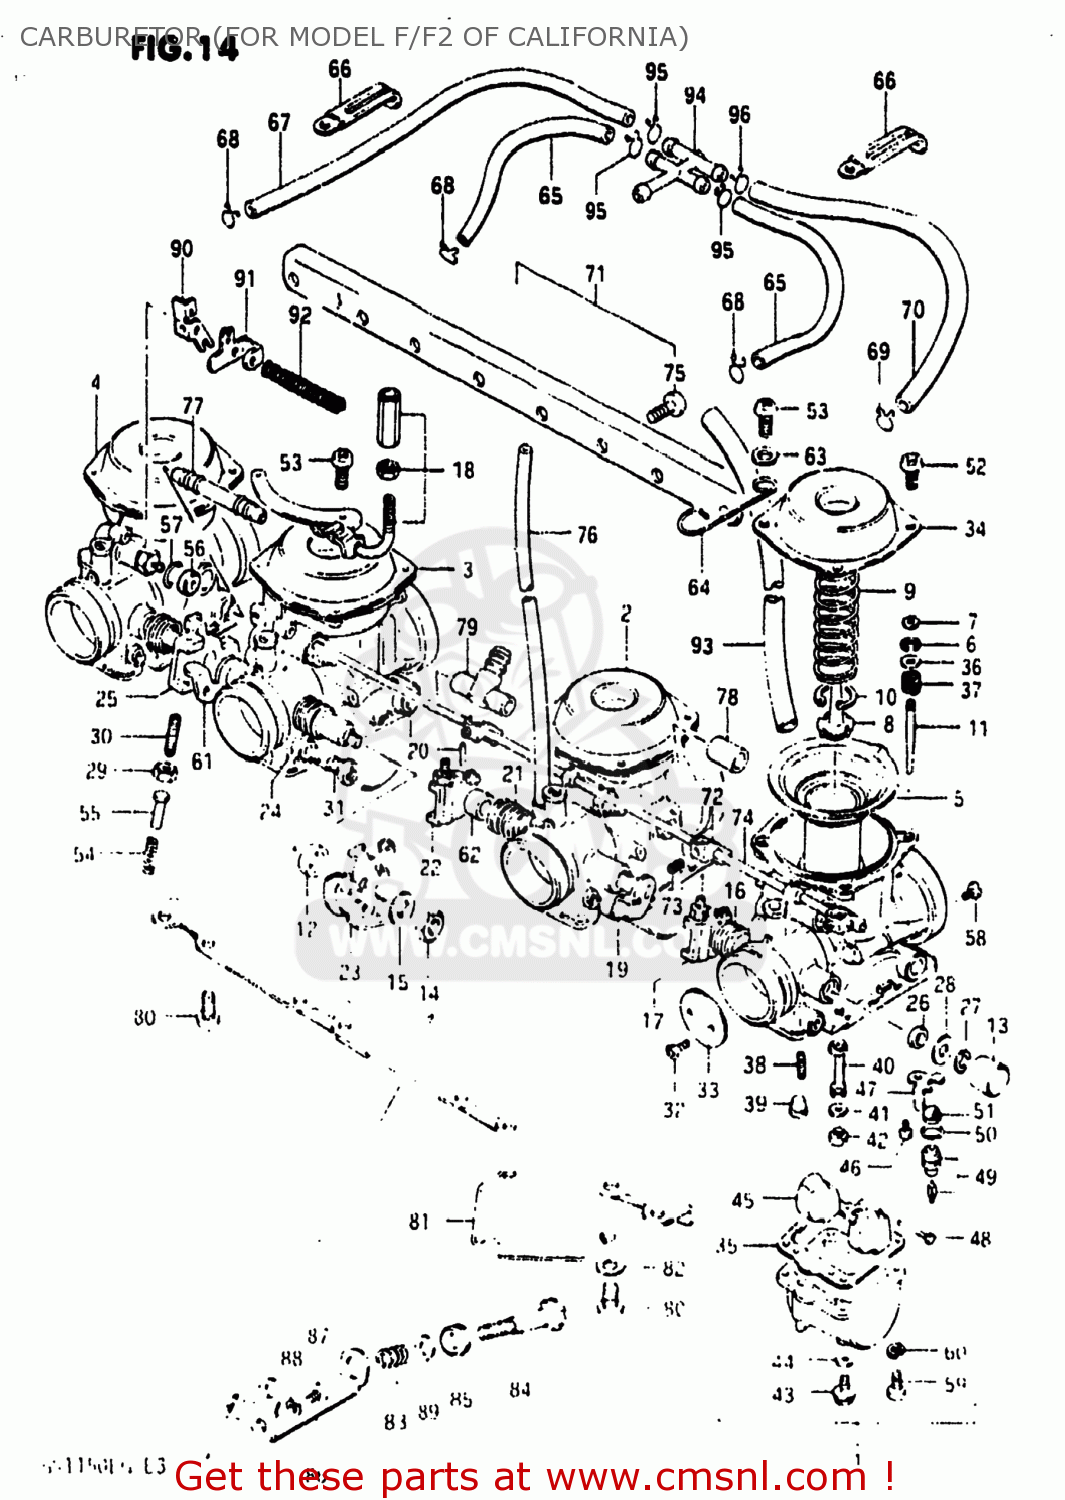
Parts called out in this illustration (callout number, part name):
1	CARBURETOR ASSEMBLY
2	CARBURETOR ASSEMBLY
3	CARBURETOR ASSEMBLY
4	CARBURETOR ASSEMBLY
5	DIAPHRAGM,CARBURETOR
6	CLIP,NEEDLE
7	RING
8	HOLDER,GUIDE
9	SPRING
10	E RING
11	NEEDLE JET
12	GASKET
13	CAP,THROTTLE SHAFT
14	NUT 8MM
15	WASHER
16	SPRING,THROTTLE SHAFT
17	SHAFT,THROTTLE
18	BRACKET
19	SHAFT,THROTTLE
20	PIN,THROTTLE SHAFT
21	SPRING,THROTTLE SHAFT
22	LEVER,THROTTLE SHAFT
23	LEVER ASSEMBLY,THROTTLE
24	SPRING,THROTTLE SHAFT
25	SHAFT,THROTTLE
26	SEAL
27	E RING
28	GASKET,THROTTLE SHAFT (NAS)
29	NUT
30	SCREW
31	SCREW
32	SCREW
33	VALVE
34	COVER,DIAPHRAGM
35	GASKET,FLOAT CHAMBER (NAS)
36	WASHER
37	SPRING
38	JET,PILOT(45)
39	PLUG,NEEDLE JET
40	JET,NEEDLE
41	WASHER,NEEDLE NOZZLE
42	JET,MAIN(120)
43	PLUG,DRAIN
44	GASKET (NAS)
45	FLOAT
46	SCREW 4X6
47	PLATE,NEEDLE VALVE FITING
48	PIN,FLOAT
49	VALVE ASSEMBLY,NEEDLE
50	O-RING,NEEDLE VALVE
51	FILTER
52	SCREW
53	SCREW
54	SPRING,THROTTLE SCREW
55	PIN,THROTTLE LEVER
56	CAP,STARTER VALVE
57	O RING
58	JET,AIR
59	SCREW
60	WASHER,LOCK
61	SHAFT,THROTTLE
62	SPACER,THROTTLE SHAFT
63	WASHER
64	CLIP
65	HOSE
66	CLAMP L:35
67	HOSE
68	CLIP
69	CLIP
70	HOSE
71	CARBURETOR ASSEMBLY
72	LEVER
73	SCREW
74	SHAFT,STARTER
75	SCREW
76	HOSE
77	NIPPLE
78	HOSE
79	NIPPLE
80	SCREW
81	CLIP
82	WASHER
83	SPRING
84	ADJUSTER
85	BUSH
86	BRACKET
87	SCREW
88	WASHER,LOCK
89	WASHER
90	LEVER
91	LEVER
92	SPRING
93	HOSE
94	DUCT,FAN COOLING NO.1
95	CLIP
96	CLIP
